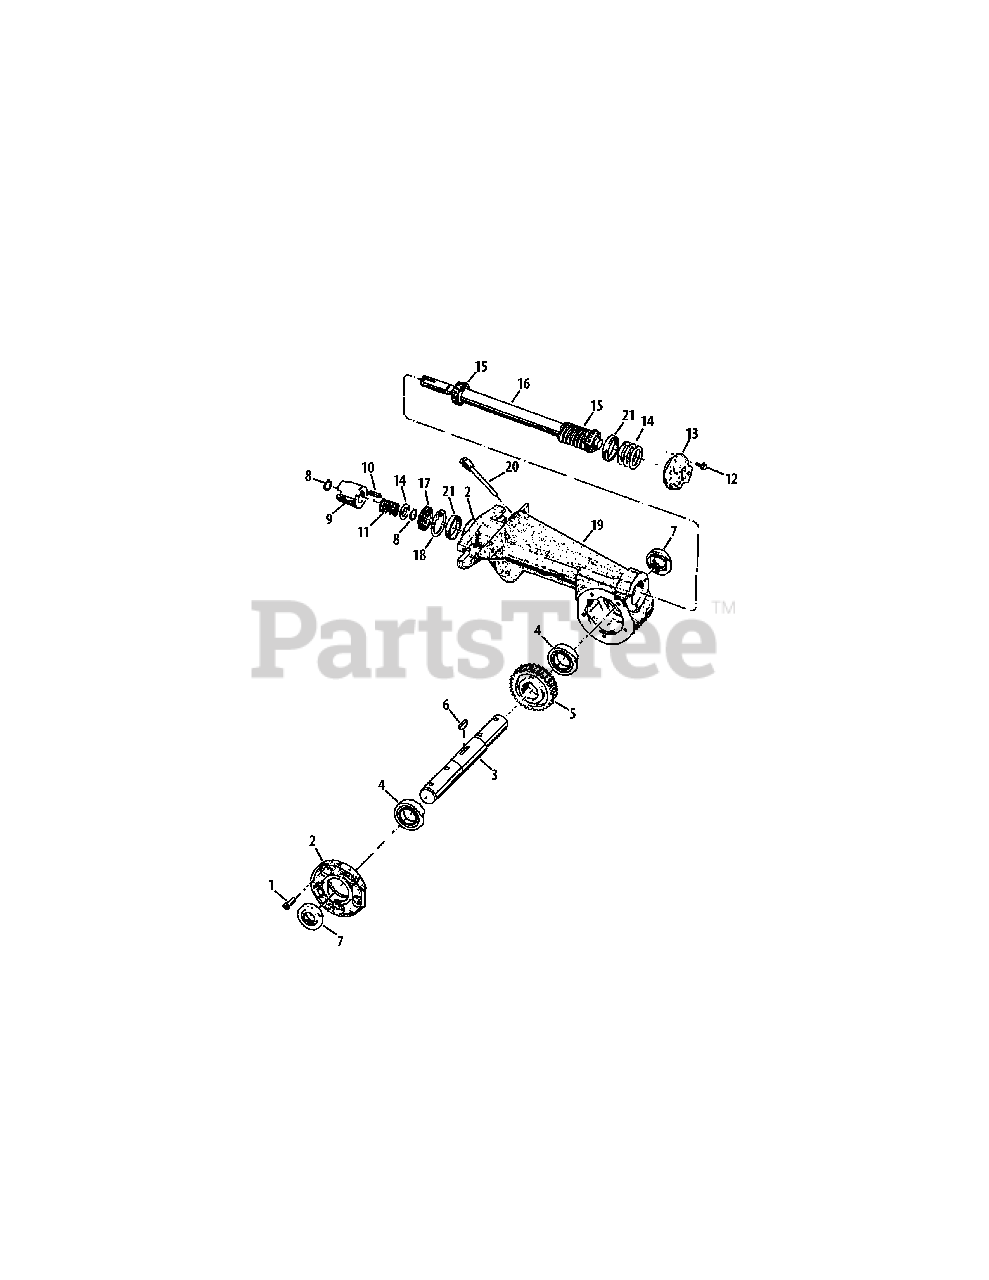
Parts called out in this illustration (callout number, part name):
1	Self-Sealing Screw, 1/4"-20 x 5/8"*
2	Tiller Housing Cover
3	Tine Shaft
4	Ball Bearing
5	Worm Gear
6	Woodruff Key
8	External Retaining Ring
9	Dog Clutch
10	Key, 3/16" x 1"
12	Self-Sealing Screw, 1/4"-20 x 7/8"*
14	Flat Washer, 1.75 x 1.5 x .062
14	Flat Washer, 1.75 x 1.5 x .005
14	Flat Washer, 1.75 x 1.5 x .03
14	Flat Washer, 1.75 x 1.5 x .01
15	Cone Bearing
18	Retaining Ring
19	Attachment Housing
20	Oil Dipstick
21	Cup Bearing
